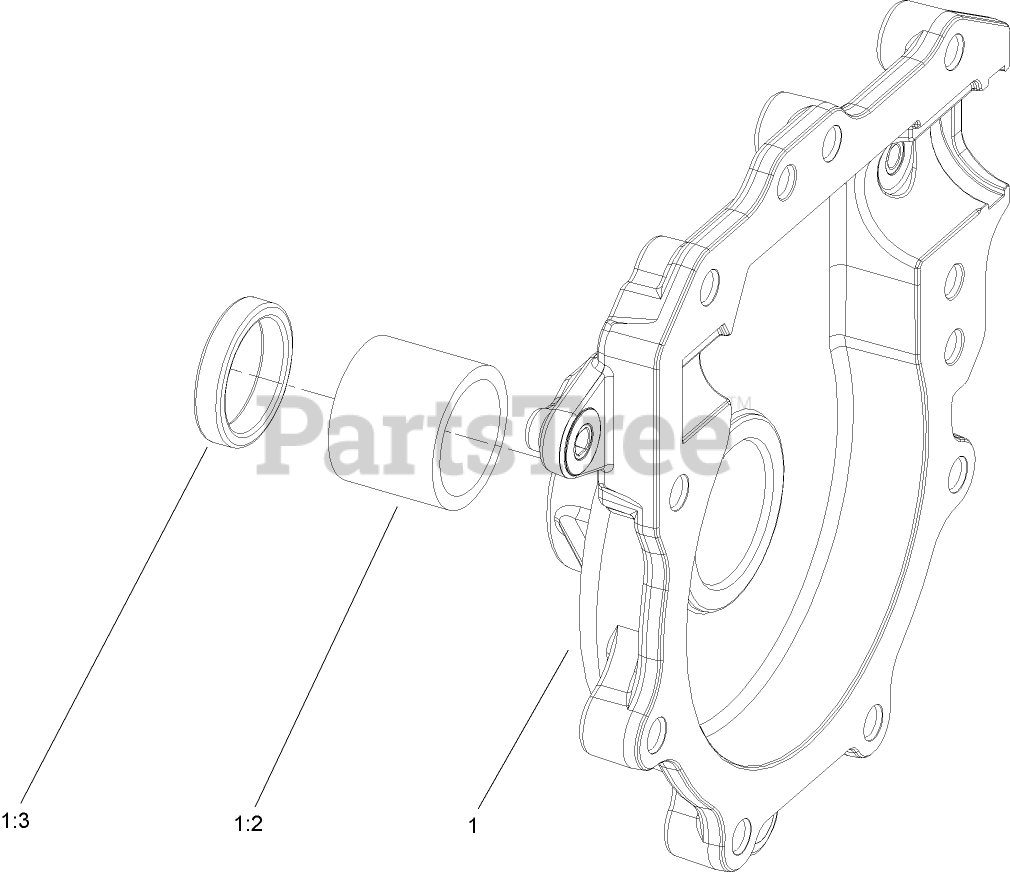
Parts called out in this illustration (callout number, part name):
1	Loose Parts Package
1:2	BUSHING
1:3	SEAL-OIL
